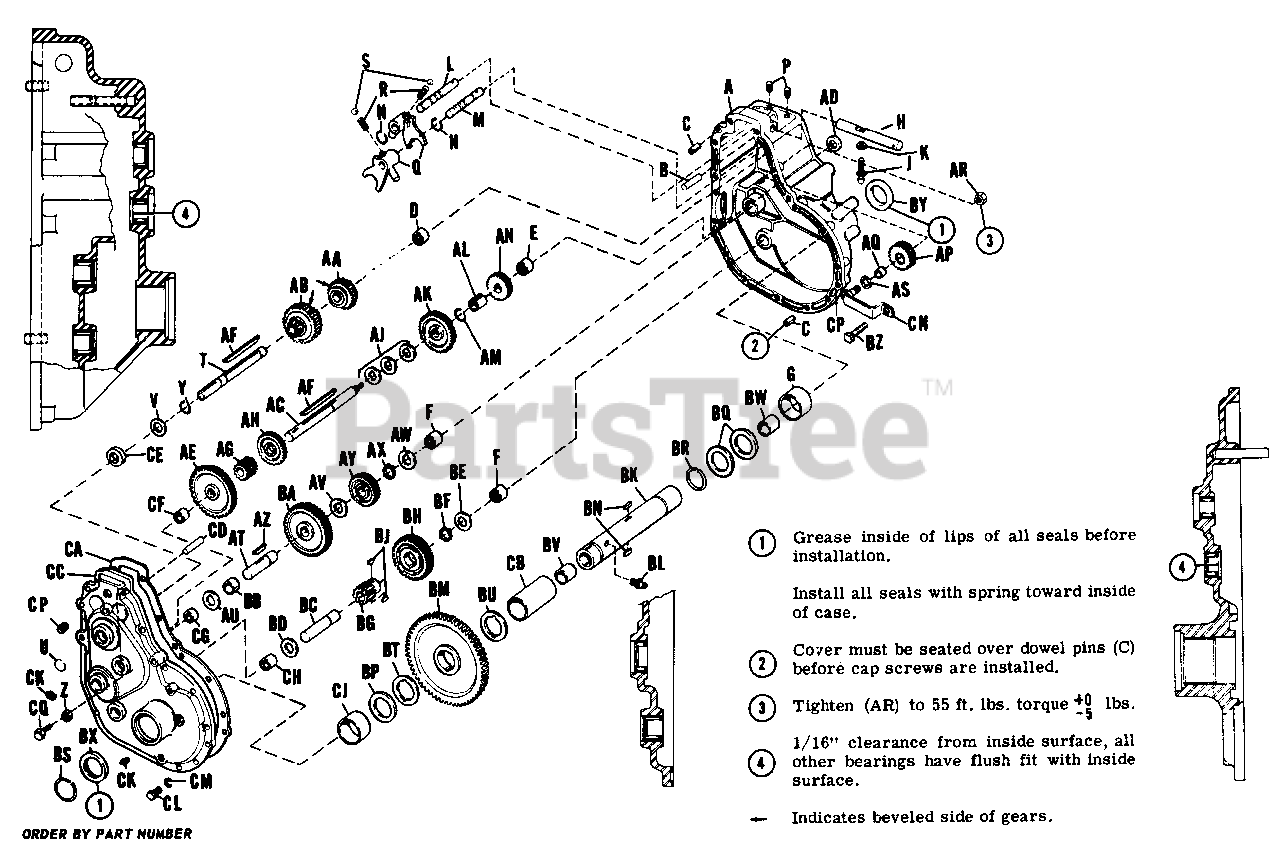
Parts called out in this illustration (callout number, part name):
A	Case, Gear, Complete w/bearings and dowel pins (Includes "B" thru "G")
D	Needle Bearing
E	Needle Bearing
F	Needle Bearing
G	Axle Tube Bearing
H	Shift Rod
J	Shift Stem
K	Full Hex. Nut, 3/8"-24 N.F.
L	Shifter Shaft Rev., Med.
M	Shifter Shaft High, Low
N	Retaining Ring
P	Set Screw, Hollow Head, Cone Point, 5/16"-18 x 1/2"
S	Shift Lock Ball
T	Pulley Shaft
U	Retaining Ring
Y	Retaining Ring
Z	Hex. Nut Jam, 5/16"-18
AA	Pinion Assembly Rev. II
AB	Pinion Assembly, I and III
AC	Shaft, 1st Intm.
AE	Driven I, Gear
AG	Pinion, 1st Intm.
AH	Pinion, Driven, III
AJ	Trans. Gear Spacer
AK	Driven II Gear
AM	Retaining Ring
AN	Reverse Pinion
AP	Reverse Gear
AQ	Rev. Gear Spacer
AR	Lock Nut, 1/2"-20 N.F.
AT	Shaft, 2nd. Intm.
AX	Retaining Ring
AY	Pinion, 2nd. Intm.
BA	Gear, 2nd. Intm.
BC	Shaft, 3rd. Intm.
BF	Retaining Ring
BG	Pinion, 3rd. Intm.
BH	Gear, 3rd. Intm.
BJ	Key Woodruff
BK	Axle Tube w/bushing
BL	Grease Fitting
BM	Drive Gear
BT	Axle Tube Washer
BU	Axle Tube Washer
BZ	Hex. Cap Screw, 3/8"-16 x 1-1/4"
CA	Gear Case Gasket
CB	Axle Tube Spacer
CC	Gear Case Cover, Complete w/bearings
CE	Ball Bearing
CF	Needle Bearing
CG	Needle Bearing
CH	Needle Bearing
CJ	Axle Tube Bearing
CK	Pipe Plug, 3/8"
CL	Hex. Cap Screw, 5/16"-18 x 1"
CM	Lock Washer, 5/16"
CN	Rev. Gear Pin Assembly
CP	Pipe Plug, 3/8"
CQ	Hex. Cap Screw, 5/16"-18 x 1-1/4"
